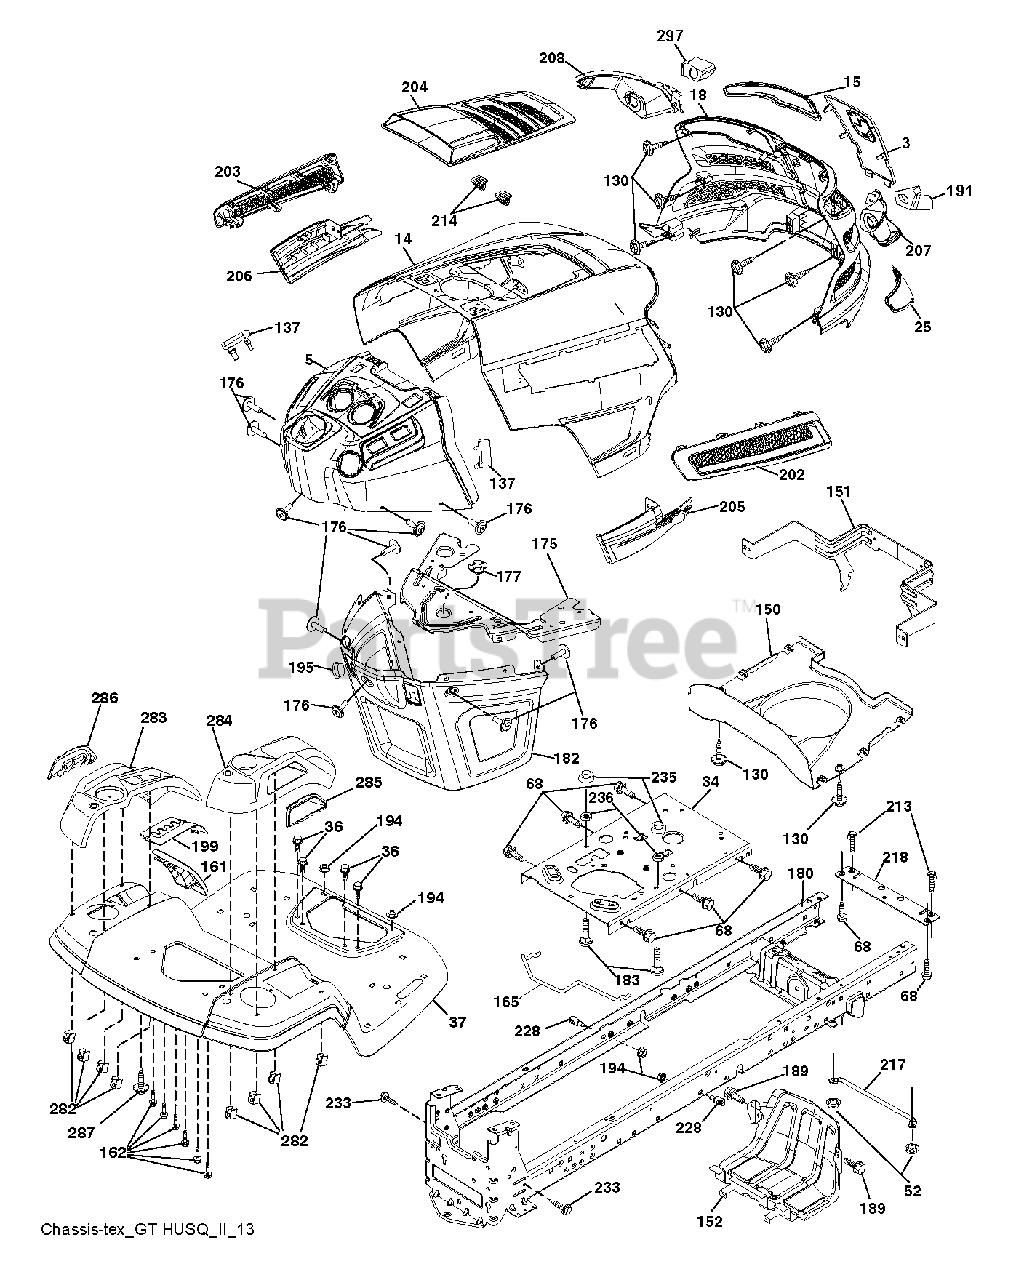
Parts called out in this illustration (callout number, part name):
3	APPLIQUE.SUBASM.GT.HUSQ.II
5	DASH.UPR.ASSY.GT2.SRVMNDER.PTO
14	HOOD.ASM.HUSQVARNA.GT.TEX.422
15	LENS.HEADLIGHT.LH.GTII.2011
18	GRILLE.SUBASM.GT.HUSQ.II
25	LENS.HEADLIGHT.RH.GTII.2011
34	PLATE.ENGINE.WELDED.CHASSIS
36	SCREW 5/16"
37	FENDER.TLT.FS.W/CPH/FW/RSF.ORN
52	LOCKNUT
68	SCREW LT
130	SCREW.#10 X 0.750.BOS
137	BUMPER DASH
150	AIR.DUCT.GTV.BLACK
151	BRACKET.PIVOT.HOOD.GT.HUSQ.II
152	SHIELD.BROWNING.W/TEX
161	WINDOW.FUEL.LT.HUSQ.TEX.498
162	SCREW.HI-LO.CONSOLE
165	SUPPORT.TANK.REAR.W/TEX
175	PLATE.CROSSMEMBER.HUSQ
176	SCREW.#10-24X5/8.RN.QU
177	BUSHING, STEERING
180	CHASSIS
182	DASH.LOWER.COMMON.12V.ADAPTOR
183	BOLT.5/16-18X1-1/4 FULL THD
189	SCREW
191	INSERT.REFLECTIVE.RH.HUSQ.GTII
194	NUT LOCK HEX FLANGE 5/16-18
195	PLUG.HOLE.DASH.LOWER.12V.BLK
199	PLATE.DECK.LIFT.HUSQ.LT
202	VENT.SIDE.RH.GT.HUSQ.II.
203	VENT.SIDE.LH.GT.HUSQ.II.498
204	VENT.TOP.HUSQ.GT2
205	SIDE.TRIM.RH.GT.HUSQ.II
206	SIDE.TRIM.LH.GT.HUSQ.II.GRAY
207	BEZEL LIGHT.RH.GT.II.MYLAR
208	BEZEL LIGHT.LH.GT.II.MYLAR
213	BOLT
214	CLIP.RETAINER.TINNER.
217	ROD.PIVOT.HOOD
218	X-PIECE.HOOD.STOP.NON/
228	STUD.FASTNER.W/ANTI-ROTATE
233	BOLT.SHOULDER
235	SPACER FENDER
236	NUT.CENTERLOCK.5/16-
282	CLIP.RETAINER.CONSOLE.LT.HUSQ
284	CONSOLE.SHFT.PDL.CNTRL.HUSQ.LT
285	CONSOLE INSERT RH
286	CONSOLE.INSRT.LH.HUSQ.LT.BLACK
287	SCREW 1/4X20
297	INSERT.REFLECTIVE.LH.HUSQ.GTII
